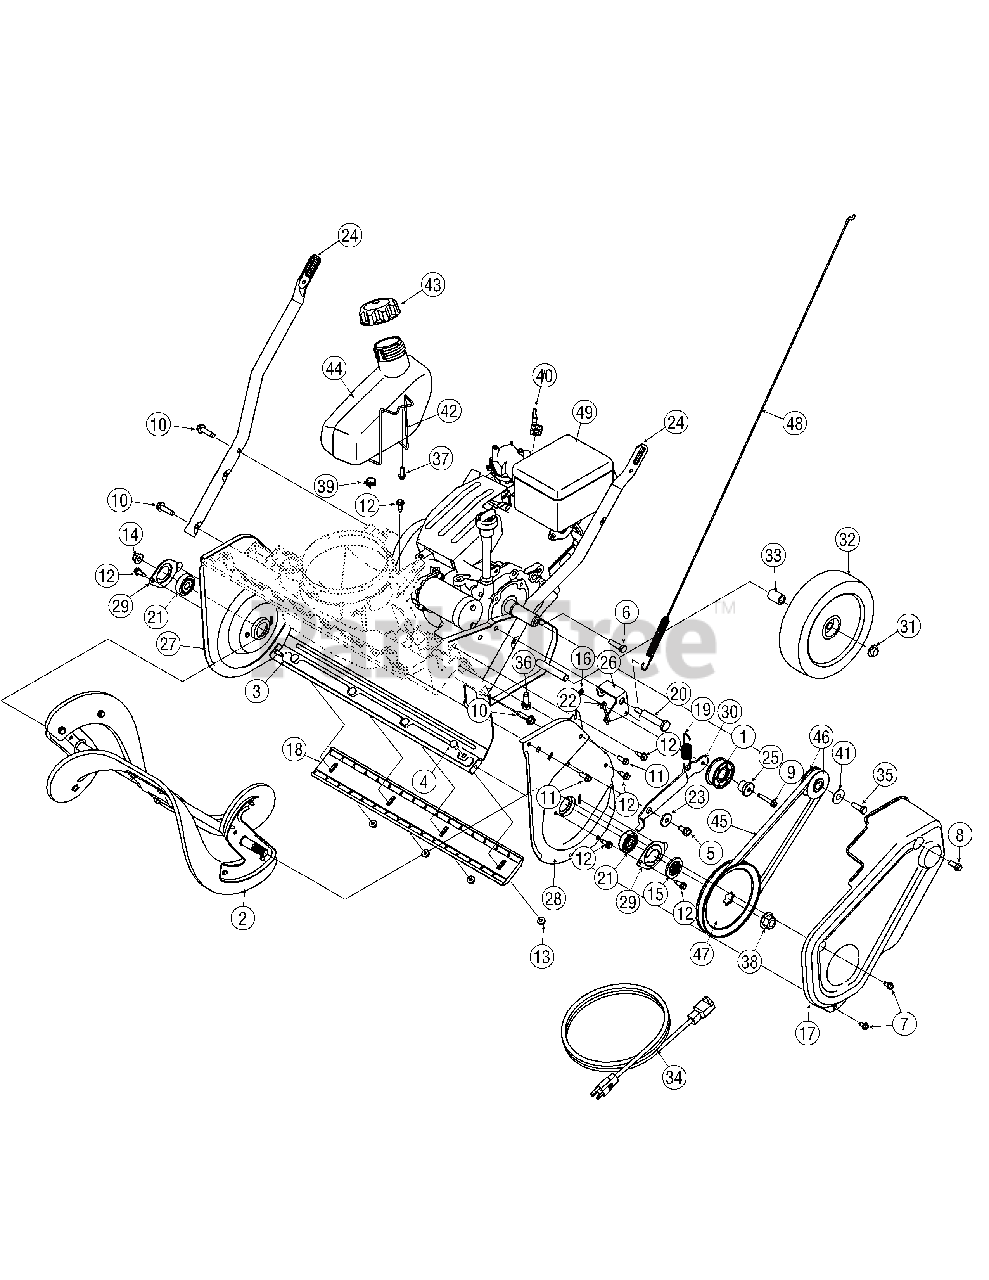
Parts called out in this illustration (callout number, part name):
1	Idler Pulley Assembly
2	Auger Assembly Complete
2	Hex Washer Screw 1/4-20 x.750
3	Frame Assembly
4	Carriage Screw, 1/4-20 x .62
5	Hex Washer Screw, 5/16-18 x .750
6	Hex Screw, 5/16-24 x 1.25
7	Hex Washer Screw, 1/4-20 x .500
8	Hex Lock Screw, 5/16-24 x .750
9	Hex Washer Screw, 1/4-20 x 1.500
10	Hex Washer Screw, 5/16-18 x 1.250
11	Hex Washer Screw, 1/4-15 x .750
12	Hex Washer Screw, 1/4-20 x .625
13	Flange Lock Nut, 1/4-20
14	Flange Lock Nut, 3/8-16
15	Pulley Hub
16	Push Nut, .25 x .50
17	Belt Cover
18	Shave Plate
19	Extension Spring, .70 x 3.035
20	Shoulder Bolt, 5/16-24 x .496 x 2.18
21	Ball Bearing, .5000 x 1.375 x .4375
22	Drive Cable Wire Support
23	Shoulder Spacer
24	Lower Handle
25	Shoulder Spacer
26	Idler Cable Bracket
27	RH Side Plate
28	LH Side Plate
29	Bearing Cup
30	Idler Bracket
31	Push Cap, 1/2
32	Wheel, 8 x 1.7
33	Sleeve Spacer, .525 x .78 x 1.07
34	Extension Cord
35	Hex Lock Screw, 5/16-24 x .750
36	Hex Washer Screw, 3/8-16 x 1.000
37	Hex Washer Screw, 1/4-15 x .750
38	Flange Nut, 7/16-20
39	Hose Clamp, .490
40	Choke Extension Lever
41	Thrust Washer, .343 x .880 x .062
42	Gas Tank Wire Support
43	Fuel Cap
44	Fuel Tank
45	Belt, .500 x 35.06
46	Pulley Half, .625 x 2.25
47	Pulley, 1/2 x 6.00
48	Clutch Cable
49	Replacement Engine
